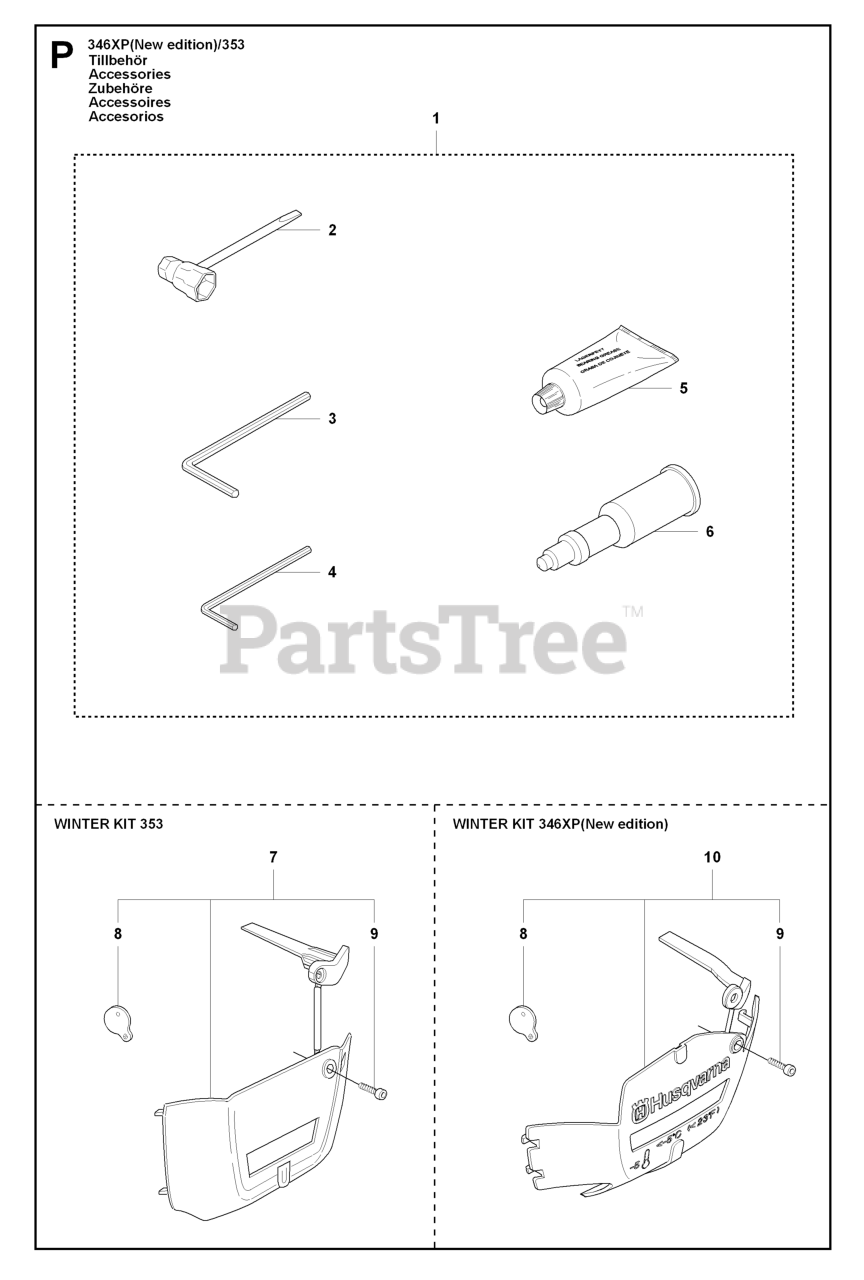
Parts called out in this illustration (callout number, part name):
1	SCRENCH
2	COMBI TOOL
5	GREASE
6	Grease Gun
7	WINTER COVER
8	COVER
10	WINTER COVER
